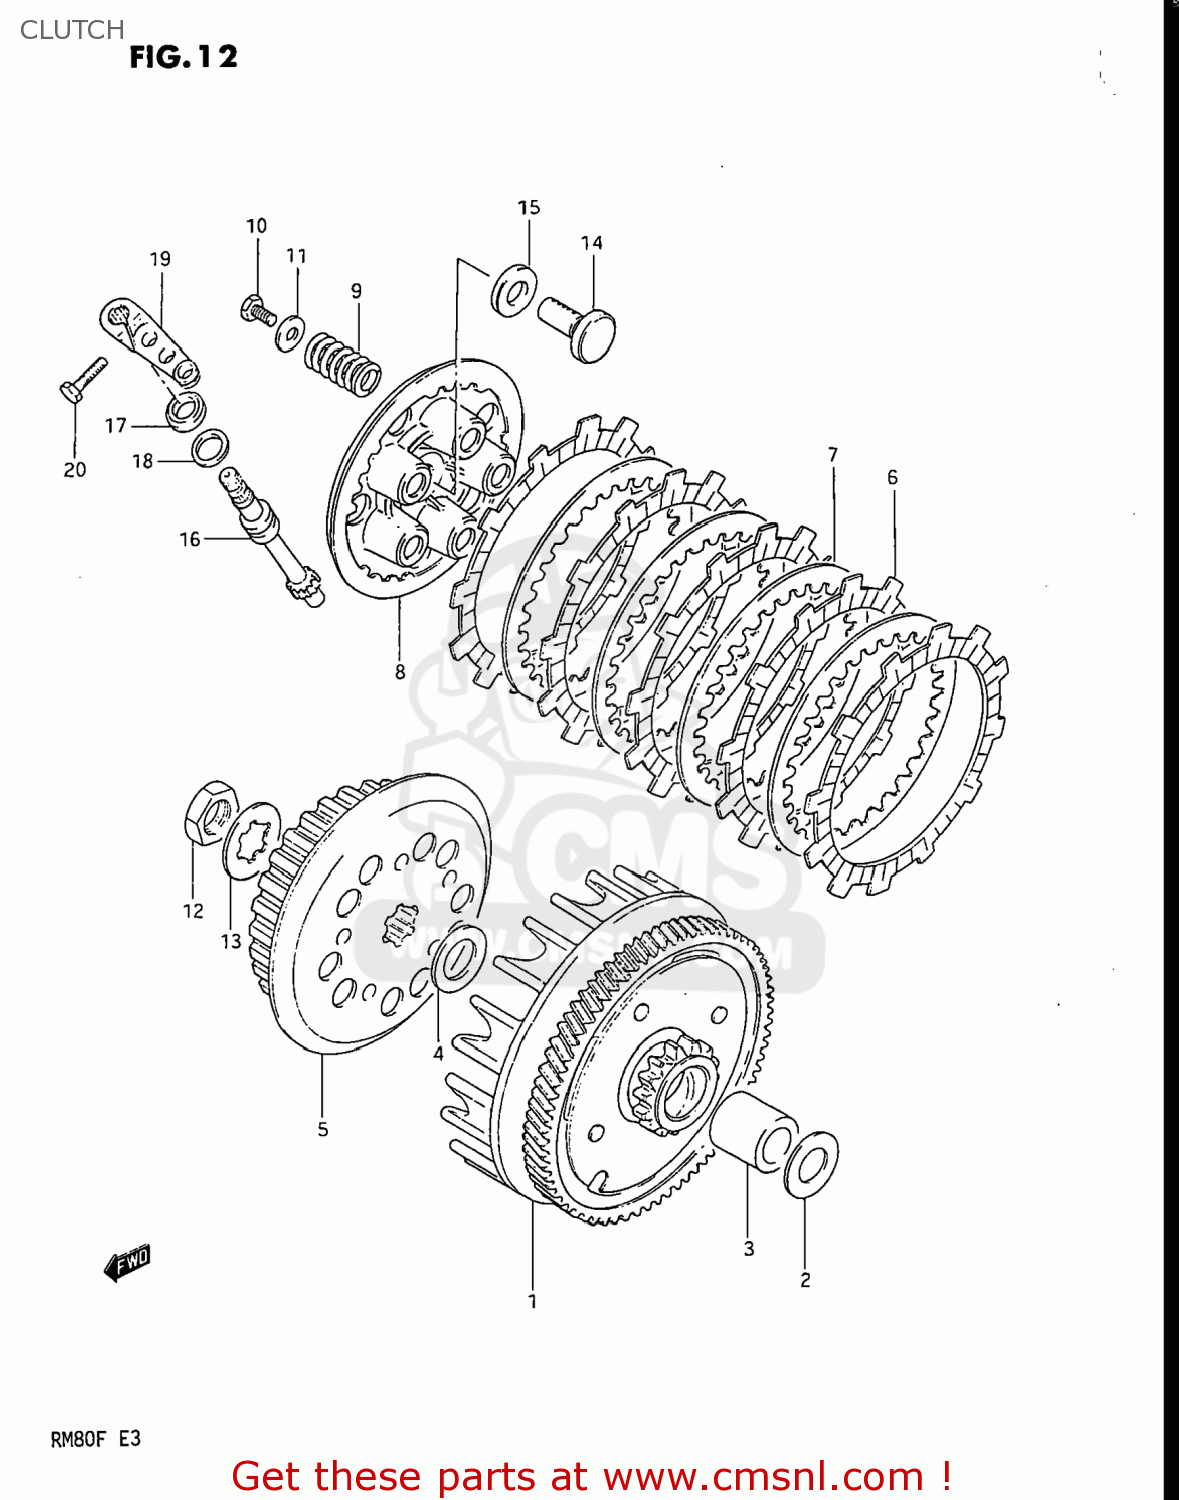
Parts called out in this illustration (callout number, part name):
1	GEAR ASSEMBLY,PRIMARY DRIVE
2	WASHER,THRUST
3	SPACER(17X22X28.5)
4	WASHER
5	HUB,CLUTCH SLEEVE
6	PLATE,CLUTCH DRIVE
7	PLATE,CLUTCH DRIVEN (NAS)
8	DISC,CLUTCH PRESSURE
9	SPRING
10	BOLT(5X16)
11	WASHER (5.5X16X1.2)
12	NUT
13	WASHER,LOCK
14	RACK,CLUTCH RELEASE
15	BEARING(10X22X2.8)
16	PINION,CLUTCH RELEASE
17	OIL SEAL
18	WASHER (12X17X1)
19	ARM,CLUTCH RELEASE
20	BOLT, UPPER
